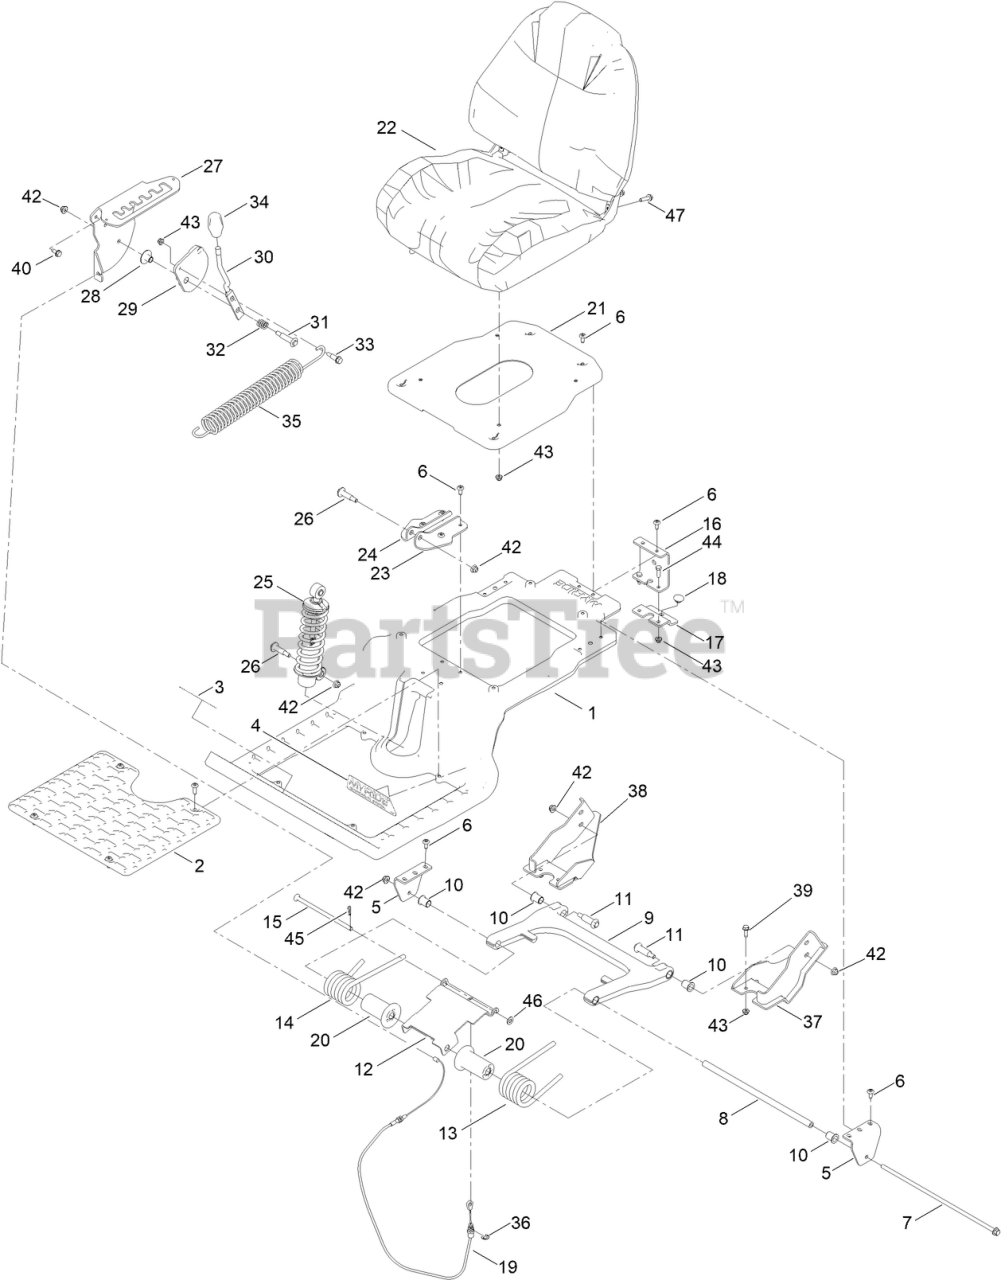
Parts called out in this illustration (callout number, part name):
1	PLATFORM, MYRIDE
2	PLATFORM, MYRIDE
3	DECAL - MYRIDE
4	DECAL - MYRIDE
5	BRACKET-MOUNT, SWING ARM
7	SCREW-HHF
8	TUBE-SPACER
9	ARM-SWING
10	BUSHING-FLANGE
11	BOLT-SHOULDER
12	PLATE-ADJUSTER
13	SPRING-TORSION, LH
14	SPRING-TORSION, RH
15	ROD-ADJUSTMENT
16	BRACKET-CABLE
17	BRACKET LOWER
18	BUMPER-SEAT
19	CABLE-ADJUSTMENT, MYRIDE
20	RETAINER-SPRING
21	PAN-SEAT
22	SEAT KING SK220 SEAT
23	BRACKET-SHOCK MOUNT, UPPER (LH)
24	BRACKET-SHOCK MOUNT, UPPER (RH)
25	SHOCK/SPRING ASM
26	BOLT-SHOULDER
27	BRACKET-MR GATE
28	BUSHING - FLANGE
29	PULLEY-CAM
30	LEVER-ADJUSTMENT, THREADED
31	BOLT-SHOULDER
32	SPRING-COMPRESSION
33	BOLT-SHOULDER, HHF
34	KNOB-MR
35	SPRING-EXTENSION
36	RING-RETAINING, EXTERNAL
37	MOUNT-MR SWING ARM, LH
38	MOUNT-MR SWING ARM, RH
39	SCREW-THD ROLL, HWH
40	SCREW-HWHTF
42	NUT-HF, NI
43	NUT-HF
44	SCREW-HH
45	PIN-HAIR
46	WASHER-FLAT
